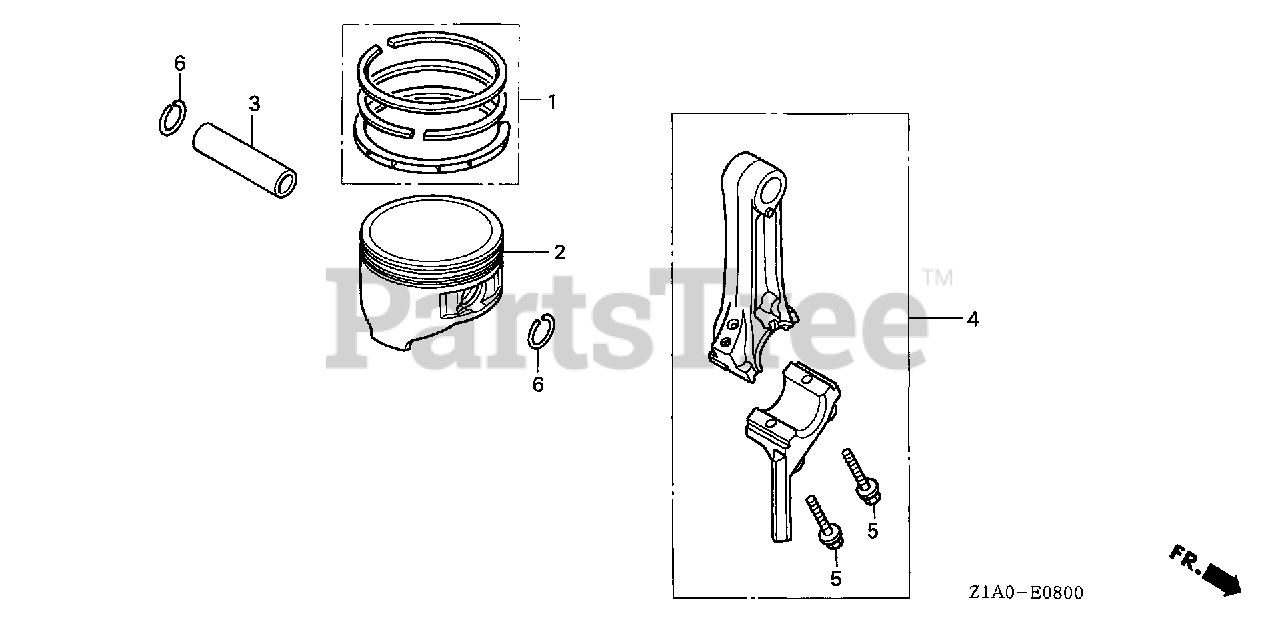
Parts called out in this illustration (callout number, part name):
1	RING SET, PISTON (STD) (TEIKOKU)
2	PISTON (NOT AVAILABLE)
3	PIN, PISTON
4	ROD ASSY., CONNECTING
5	BOLT, CONNECTING ROD
6	CLIP, PISTON PIN (13MM)
